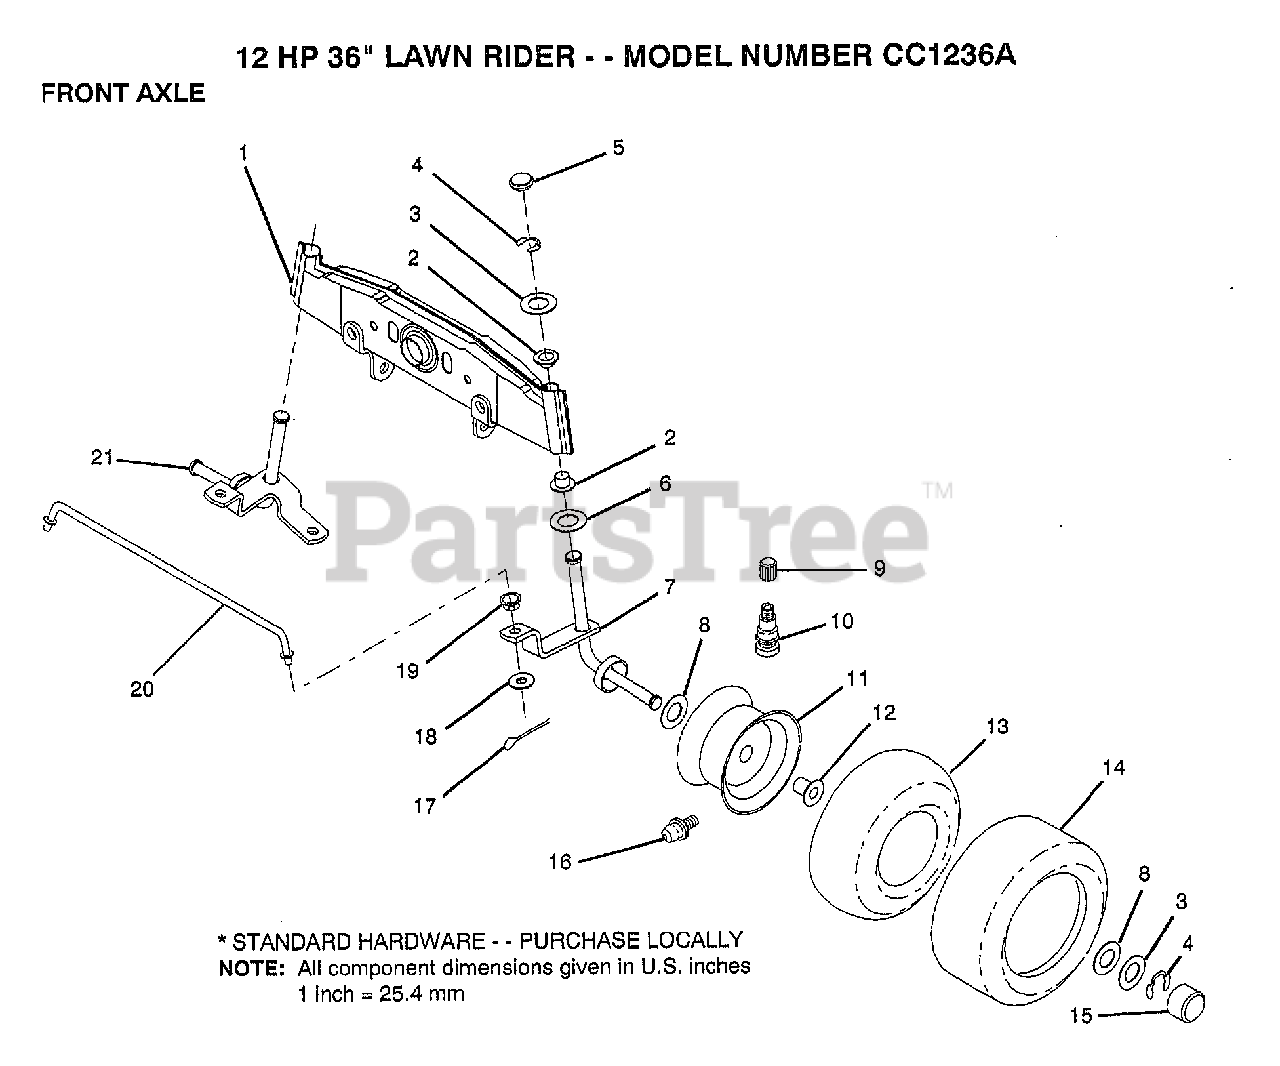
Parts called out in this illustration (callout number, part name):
2	NYLINER
3	WASHER
4	RING
5	CAP
6	WASHER .T
7	SPINDLE RH
8	WASHER
9	VALVE CAP
10	VALVE STEM LT
12	"FLANGE, BEARING"
13	TUBE.5.3/4.5/6
15	HUB CAP
16	FITTING LT
17	COTTER PIN
18	WASHER
19	BUSHING.DRAGLINK
20	ROD TIE
21	SPINDLE LH
